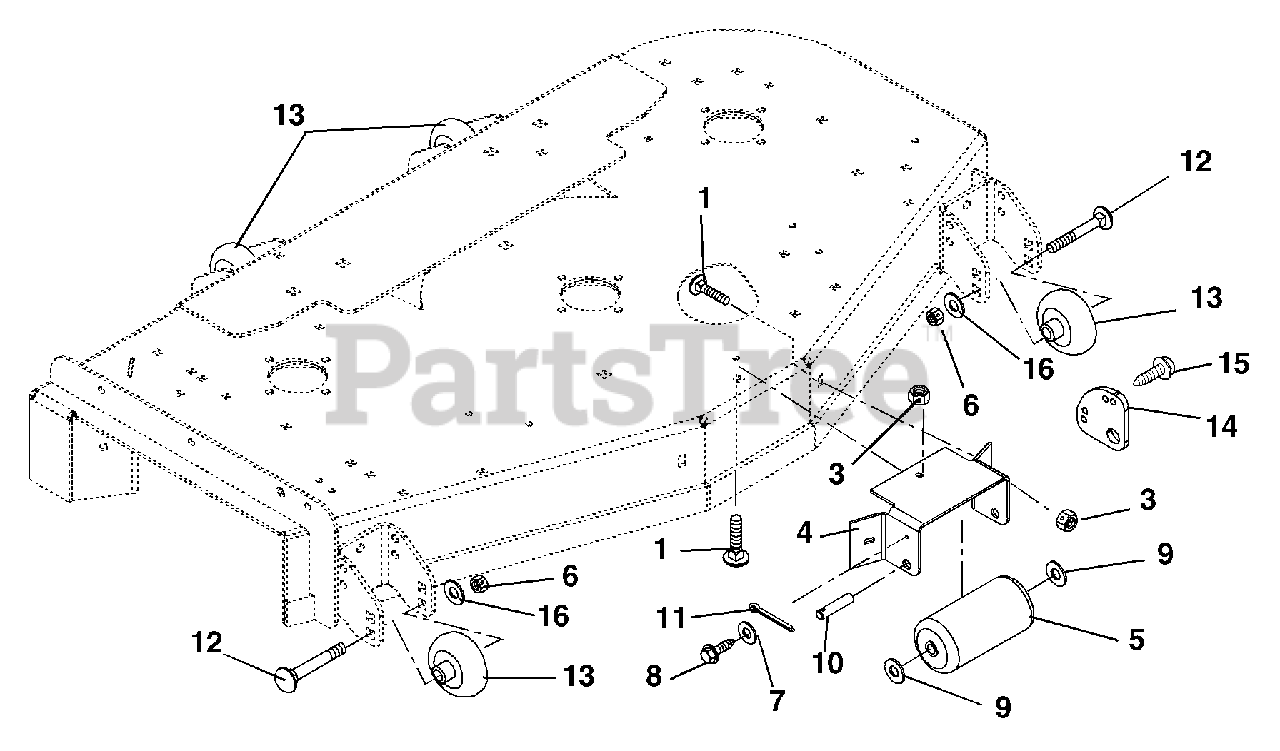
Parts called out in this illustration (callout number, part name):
1	Bolt, Round Head Square Neck .38-16 x 1.00 Grade 5) (077, 078, 079, 081, 310, 311)
2	Bolt, Round Head Square Neck .38-16 x 1.25 Grade 2 (080, 082)
3	Nut, Locking Top Flange .38-16
4	Bracket, Anti-Scalp Roller
6	Nut, Locking Nylon .50-13
7	Washer, Flat Steel .281 x .62 x .065
8	Screw, Tapping .25-20 x .75 Hex Washer Head
9	Washer, Flat Steel .656 x 1.31 x .095
11	Pin, Cotter .25 x 2.0
12	Bolt, Round Head Square Neck .50-13 x 5.00 Grade 2
13	Wheel, 3 x 5
14	Anti-Scalp Washer
15	Screw, Tapping .25-20 x .62 Hex Washer Head
16	Washer, Flat Steel .531 x 1.06 x .095
